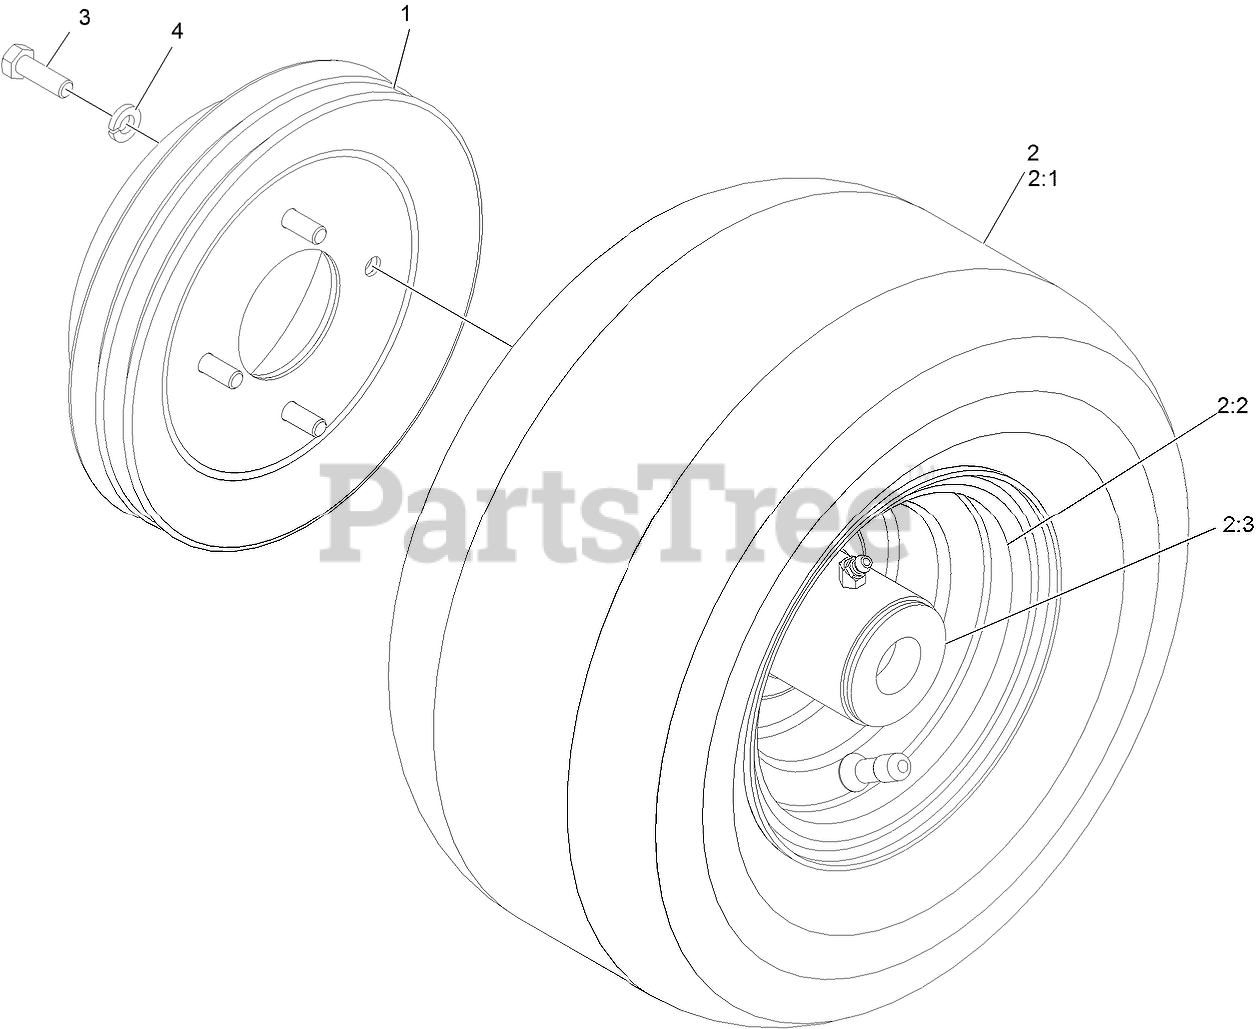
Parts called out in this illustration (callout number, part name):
1	DRUM AND SHEAVE ASM
2	WHEEL AND TIRE ASM
2:1	TIRE
2:2	WHEEL AND HUB ASM
2:3	BEARING-FLANGED
3	SCREW-HH
4	WASHER-LOCK
